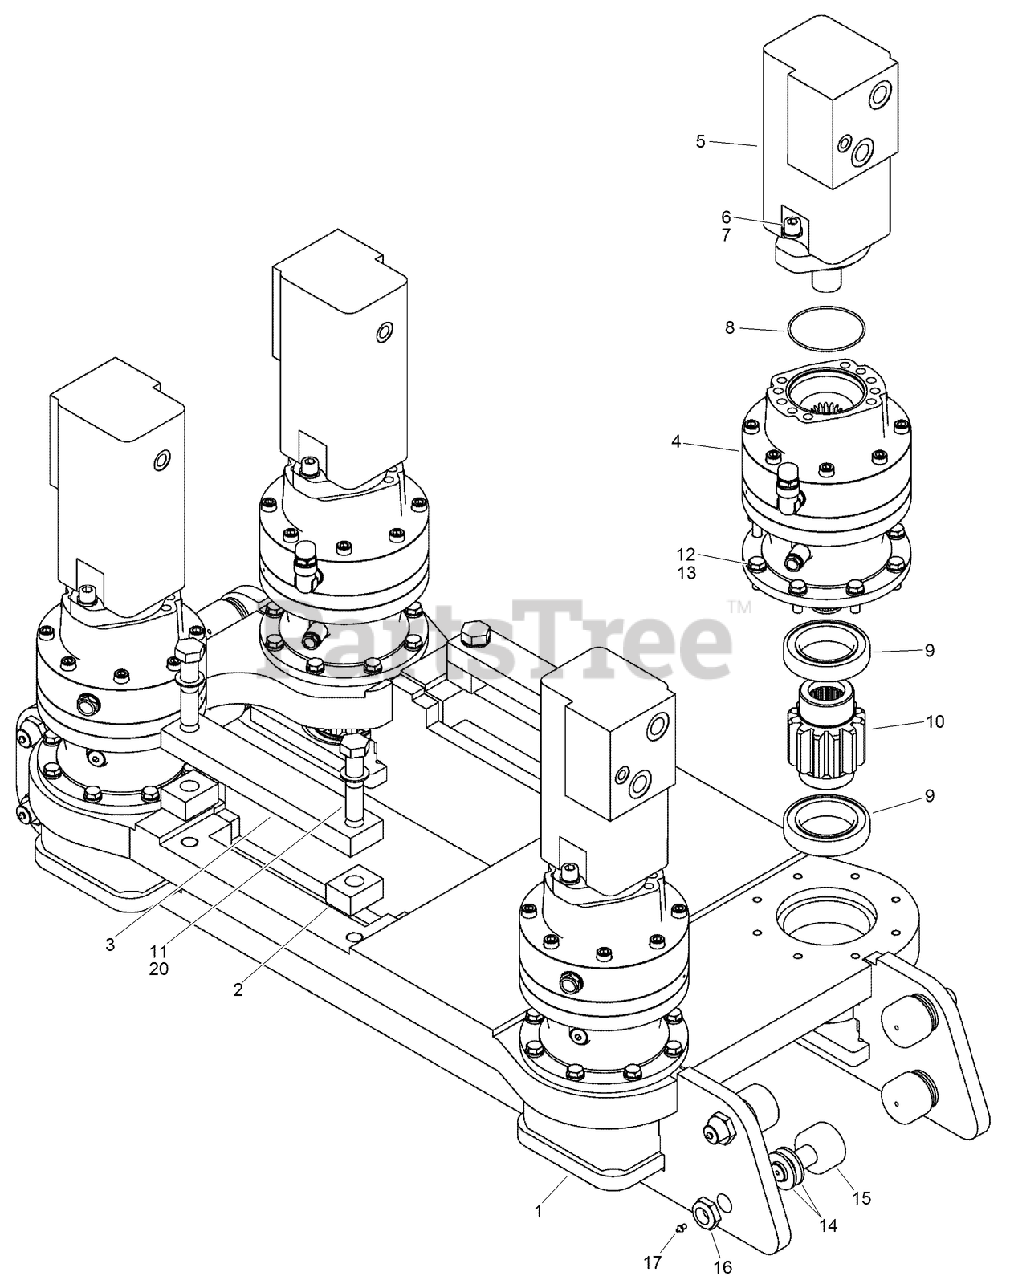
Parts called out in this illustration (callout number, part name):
1	WELDMENT - Carriage
2	SPACER - Clamp, Carriage
3	CLAMP - Rotary Box, Carriage
4	PLANETARY GEARBOX ASM
5	HYD MOTOR ASM
6	WASHER-Spring Lock Reg 1/2 ZND
7	SCREW-HSFH
9	BEARING-BALL, RADIAL
10	PINION-DRIVE, CARRIAGE
11	WASHER - Lock, Reg 0.438 in ZND
12	WASHER - Spring Lock, Reg 0.438 in ZND
13	SCREW - Cap, M10 x 30 mm
15	BEARING-FOLLOWER, CAM
16	NUT - Jam, Hex, 7/8 - 14 NF, Nyloc
17	FITTING - Lube, 3/16 Drive Type
20	SCREW-HH
